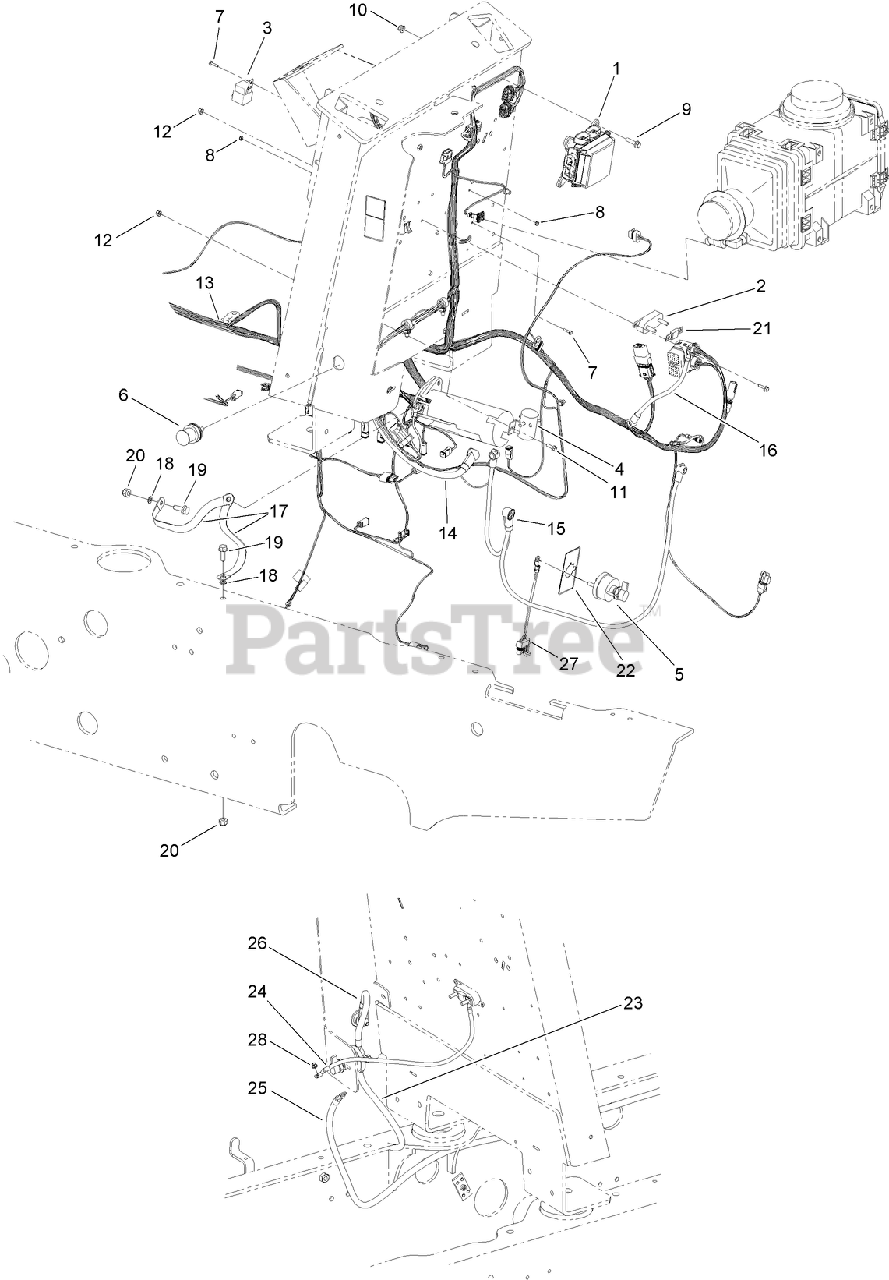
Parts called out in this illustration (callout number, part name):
1	BOX-VEHICLE, MAIN
2	HOLDER-FUSE
3	RELAY
4	SOLENOID-RELAY 12V, 300A
5	SWITCH-DISCONNECT, MASTER
6	POST-BATTERY, REMOTE
7	SCREW-HWH
8	NUT-LOCK, NI
9	SCREW-HHF
10	NUT-LOCK, HHF
11	SCREW-HHF
12	NUT-HHF
13	HARNESS-MAIN
14	CABLE-BATTERY, POSITIVE
15	CABLE-BATTERY, POSITIVE
16	CABLE-BATTERY, POSITIVE
17	STRAP-GROUNDING
18	WASHER-LOCK
19	SCREW-HHF
20	NUT-LOCK, NI
21	FUSE-100A
22	DECAL-DISCONNECT, BATTERY
23	CABLE-BATTERY, POSITIVE
24	CABLE-BATTERY, POSITIVE
25	CABLE-BATTERY, NEGATIVE
26	CABLE-BATTERY, POSITIVE
27	HARNESS-WIRE, FUSIBLE LINK
28	NUT-HHF
